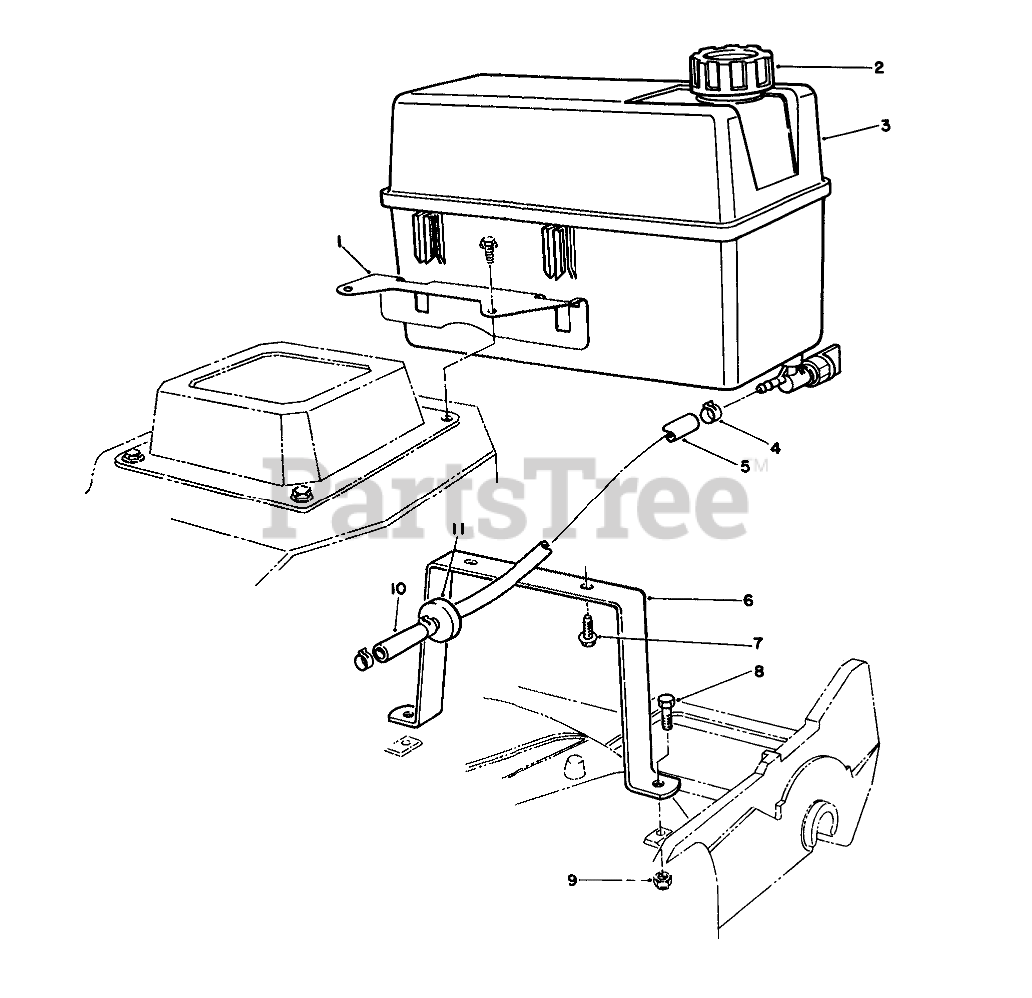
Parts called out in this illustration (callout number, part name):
1	TANK BRACKET
2	GAS CAP ASM
3	Tank-Gas
4	CLAMP-FUEL LINE
5	HOSE-FUEL
6	TANK BASE
7	SCREW-HWH
8	SCREW-HH
9	NUT-LOCK, NI
10	HOSE-FUEL
11	FILTER-FUEL
